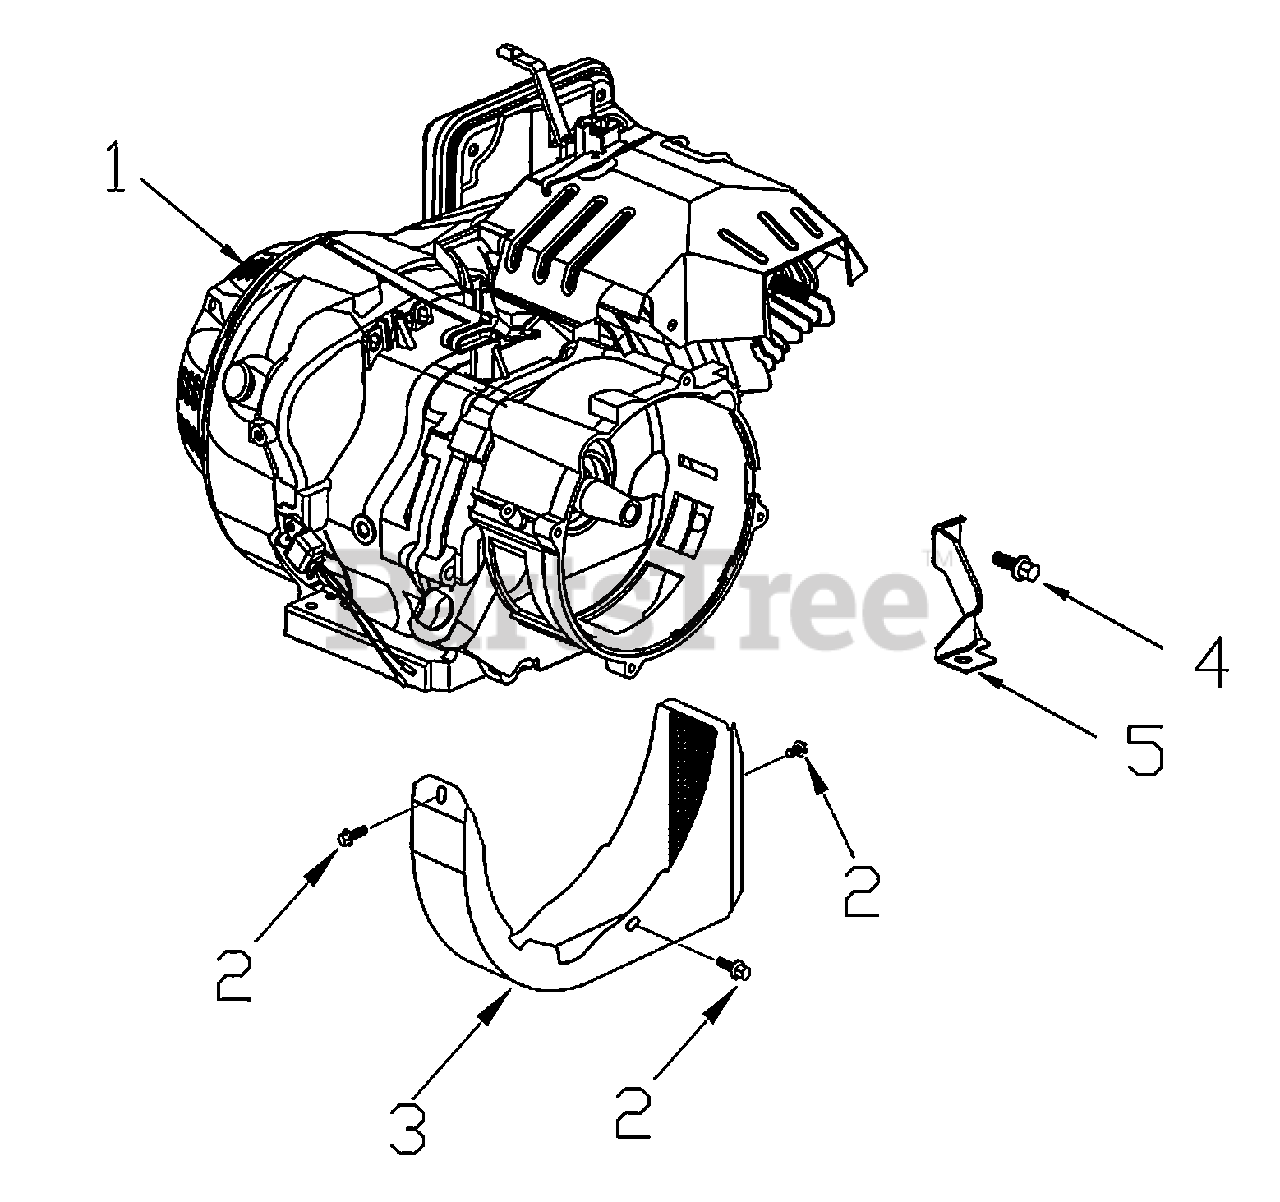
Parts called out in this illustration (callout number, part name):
1	ENGINE, 420CC, ES, W/O MFLR
2	BOLT, FLANGE M5*10
3	COVER, DUST
4	BOLT, FLANGE M6*12
5	BRACKET, AIR CLEANER
